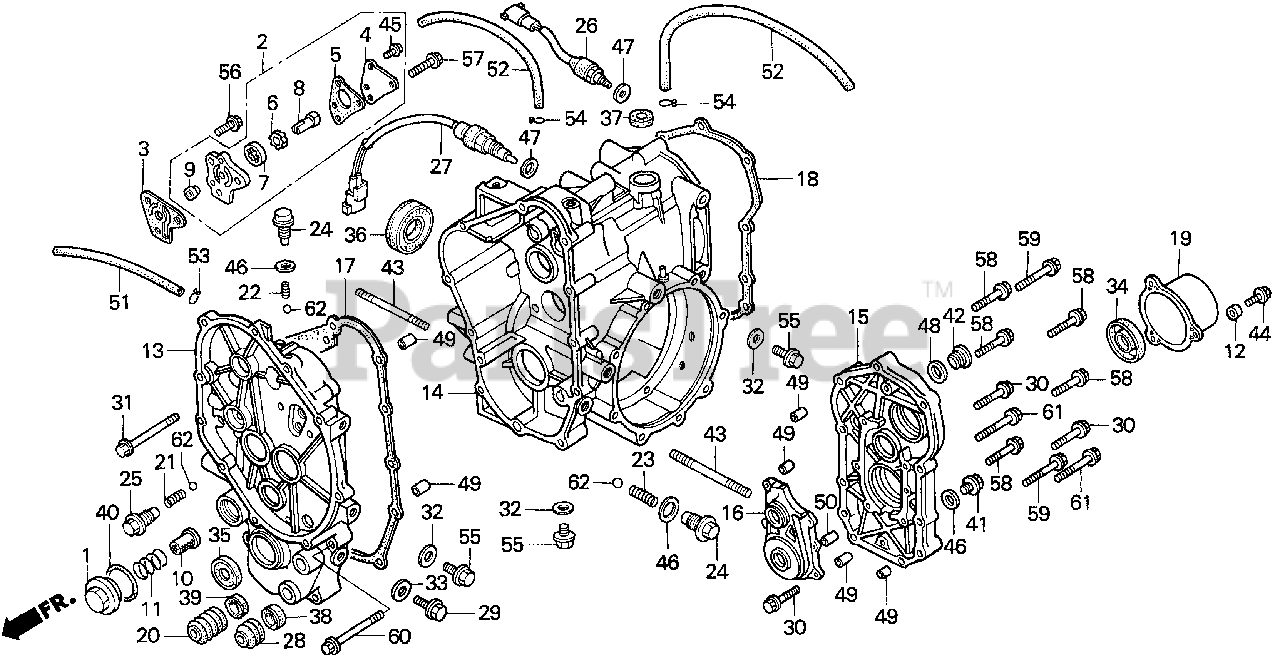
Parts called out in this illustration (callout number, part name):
1	CAP, TAPPET ADJUSTING HOLE
2	PUMP ASSY., OIL
3	GASKET, OIL PUMP BODY
4	COVER, OIL PUMP
5	GASKET, OIL PUMP COVER
6	ROTOR, OIL PUMP (INNER)
7	ROTOR, OIL PUMP (OUTER)
8	SHAFT, OIL PUMP DRIVE
9	PIN, OIL PUMP KNOCK (NOT AVAILABLE)
10	SCREEN, OIL FILTER
11	SPRING, OIL FILTER SCREEN
12	COLLAR, FAN
13	CASE, FR. TRANSMISSION
14	CASE, RR. TRANSMISSION
15	COVER, RR. TRANSMISSION
16	CASE, P.T.O. REDUCTION
17	GASKET, TRANSMISSION CASE
18	GASKET, RR. COVER
19	COVER, P.T.O.
20	BOOT, SHIFT SHAFT
21	SPRING, SET BALL INTERLOCK
22	SPRING, BALL SETTING (NOT AVAILABLE)
23	SPRING, BALL SETTING
24	SCREW, BALL SPRING SETTING
25	SCREW, BALL SPRING SETTING
26	SWITCH ASSY., RR. P.T.O.
27	SWITCH ASSY., NEUTRAL
28	BOOT, DIFFERENTIAL LOCK SHAFT
30	BOLT, FLANGE (8X40) (SEALING)
31	BOLT, FLANGE (8X45)
32	WASHER, PLAIN (10MM)
34	OIL SEAL (40X62X8)
35	OIL SEAL (22X40X8)
36	OIL SEAL (26X48X7.8)
37	OIL SEAL (12X22X6)
38	OIL SEAL (12X22X11.5)
39	OIL SEAL (14X24X11.5)
40	O-RING (35X3)
41	BOLT, DRAIN PLUG (12MM)
42	BOLT, DRAIN PLUG (20MM)
43	BOLT, STUD (10X80)
44	BOLT, SPECIAL (6MM)
44	BOLT-WASHER (6X20)
45	SCREW-WASHER (5X10)
46	WASHER, DRAIN PLUG (12MM)
47	WASHER, DRAIN PLUG (14MM)
48	WASHER, DRAIN PLUG (20MM)
49	PIN, DOWEL (10X16)
50	PIN, DOWEL (8X14)
51	BULK HOSE, FUEL (4.5X3000) (4.5X260)
52	BULK HOSE, FUEL (5.5X3000) (5.5X380)
53	CLIP, TUBE (B8)
54	CLIP, TUBE (B10)
55	BOLT, FLANGE (10X25)
56	BOLT, FLANGE (6X18)
57	BOLT, FLANGE (6X22)
58	BOLT, FLANGE (8X40)
59	BOLT, FLANGE (8X50)
60	BOLT, FLANGE (8X45)
60	BOLT, FLANGE (8X90)
61	BOLT, FLANGE (10X50)
62	BALL, STEEL (#10) (5/16)
